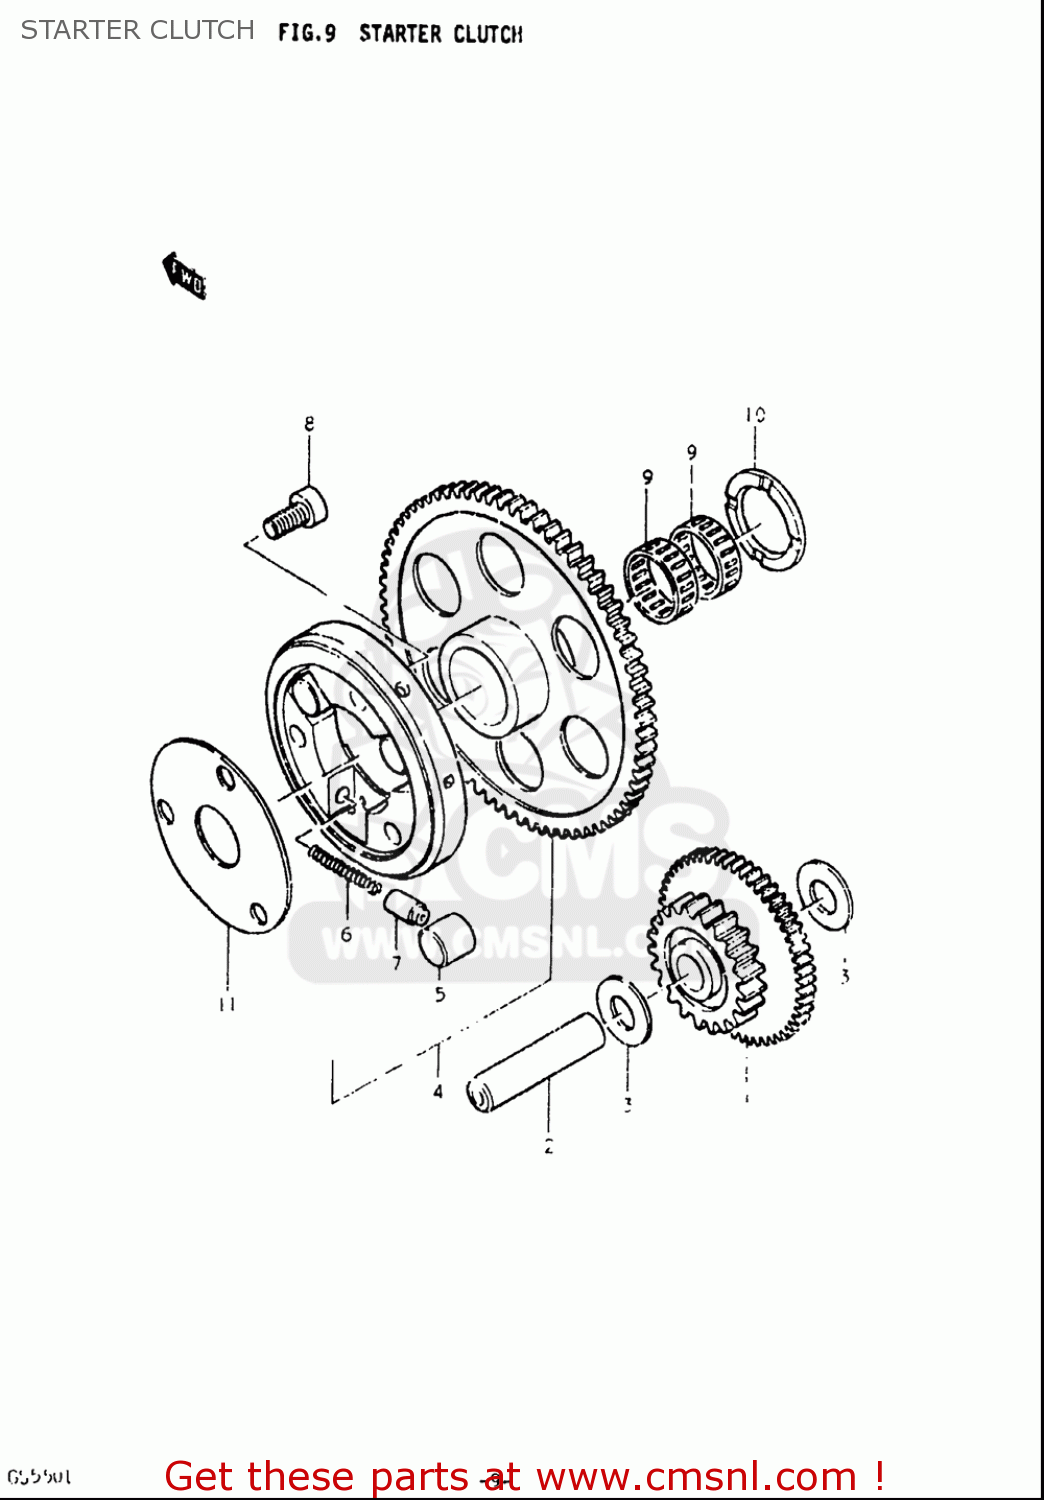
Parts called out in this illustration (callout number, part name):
2	PIN(7.4X13X56)
3	WASHER(13.3X25X0.85)
5	ROLLER(15X13)
6	SPRING
7	PIECE,PUSH
8	BOLT
9	ROLLER BEARING (25X30X9
10	WASHER(25X38X2.5)
11	SHIM,STARTER CLUTCH HUB
